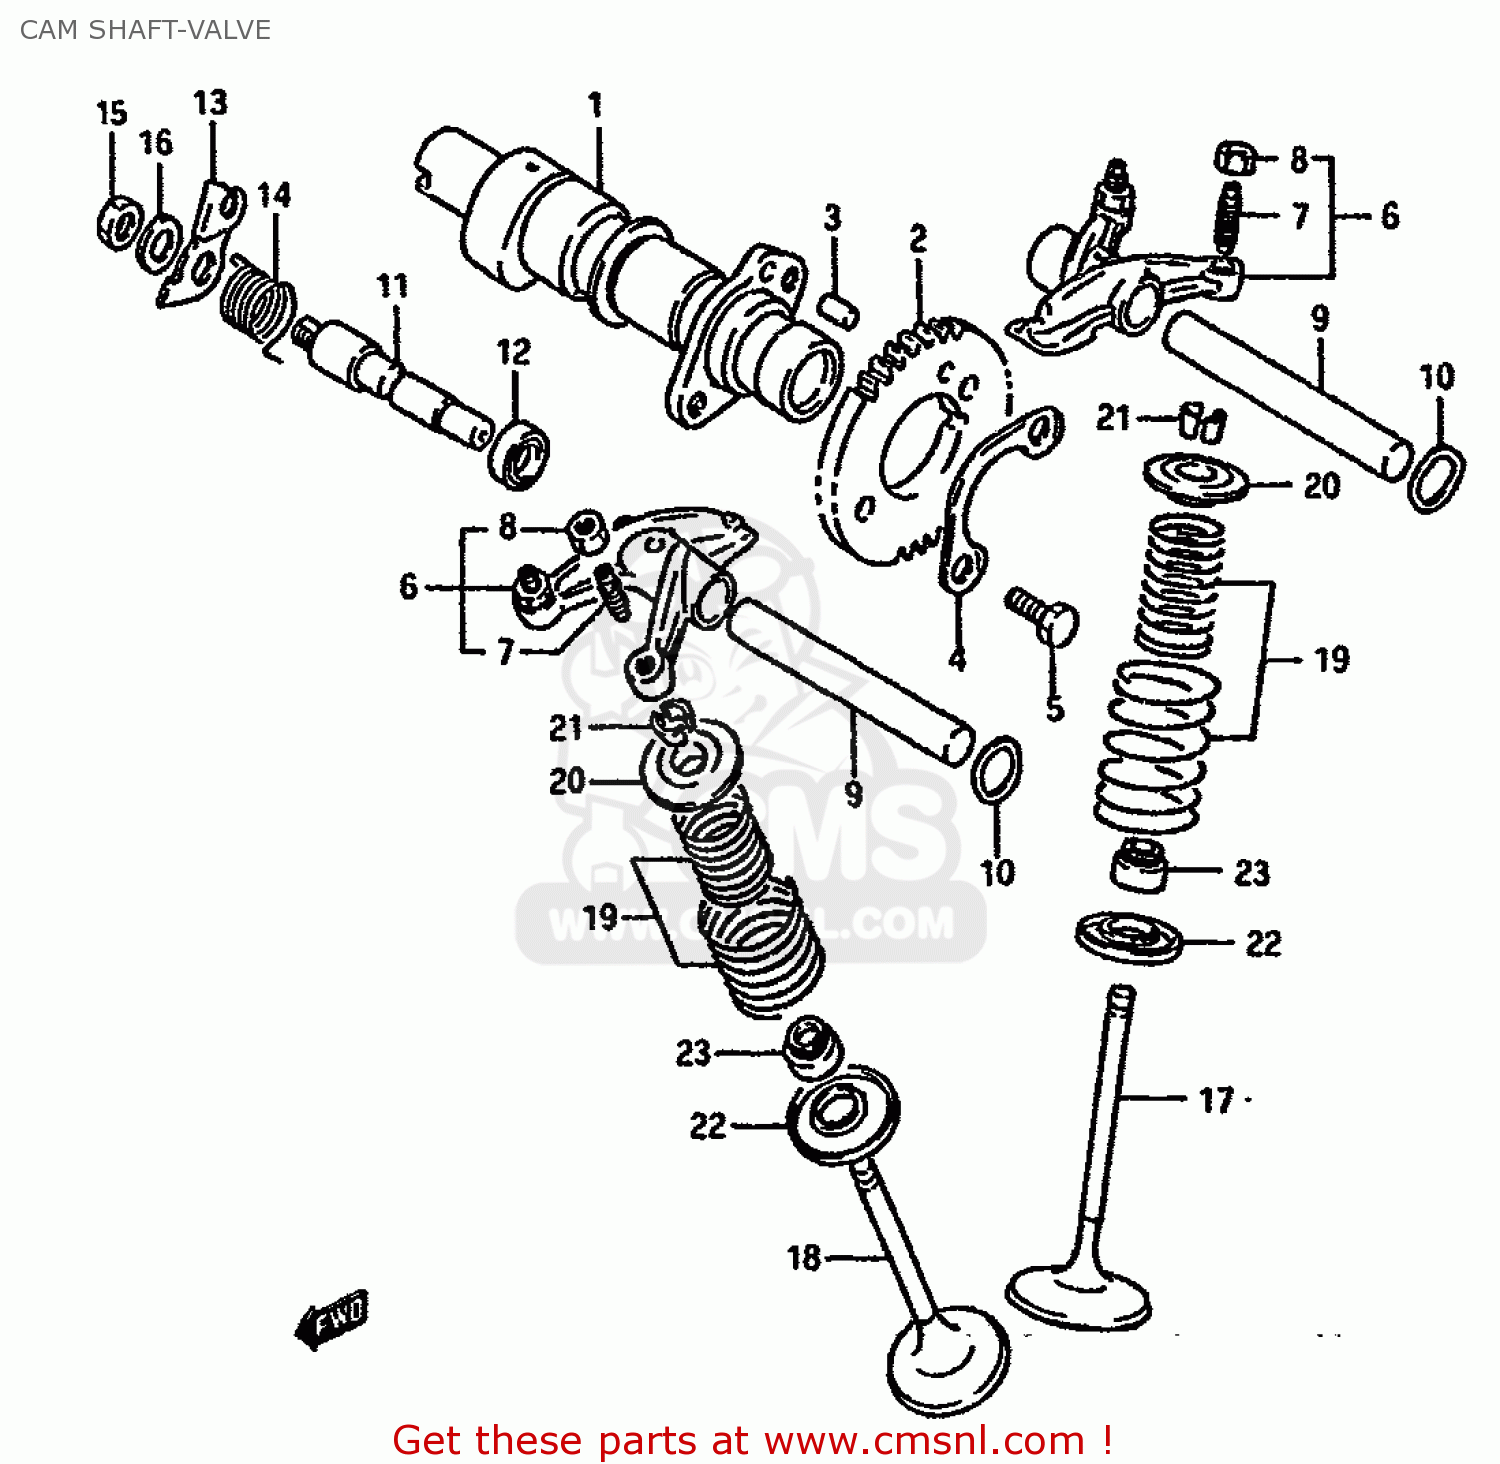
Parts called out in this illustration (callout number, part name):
1	CAMSHAFT
2	SPROCKET,CAMSHAFT
3	PIN
4	WASHER,SPROCKET
5	BOLT(6X14)
6	ARM,VALVE ROCKER
7	SCREW,TAPPET ADJUSTING
8	NUT,ADJUSTING SCREW
9	SHAFT,VALVE ROCKER ARM
10	WASHER
11	SHAFT,DECOMP
12	SEAL,OIL(10X17X6)
13	LEVER,DECOMP SHAFT
14	SPRING
15	NUT 8MM
16	WASHER
17	VALVE,INTAKE
18	VALVE,EXHAUST
19	SPRING SET,VALVE
20	RETAINER,VALVE SPRING
21	COTTER,VALVE
22	SEAT,VALVE SPRING
23	SEAL,OIL(7X14.4X9)
